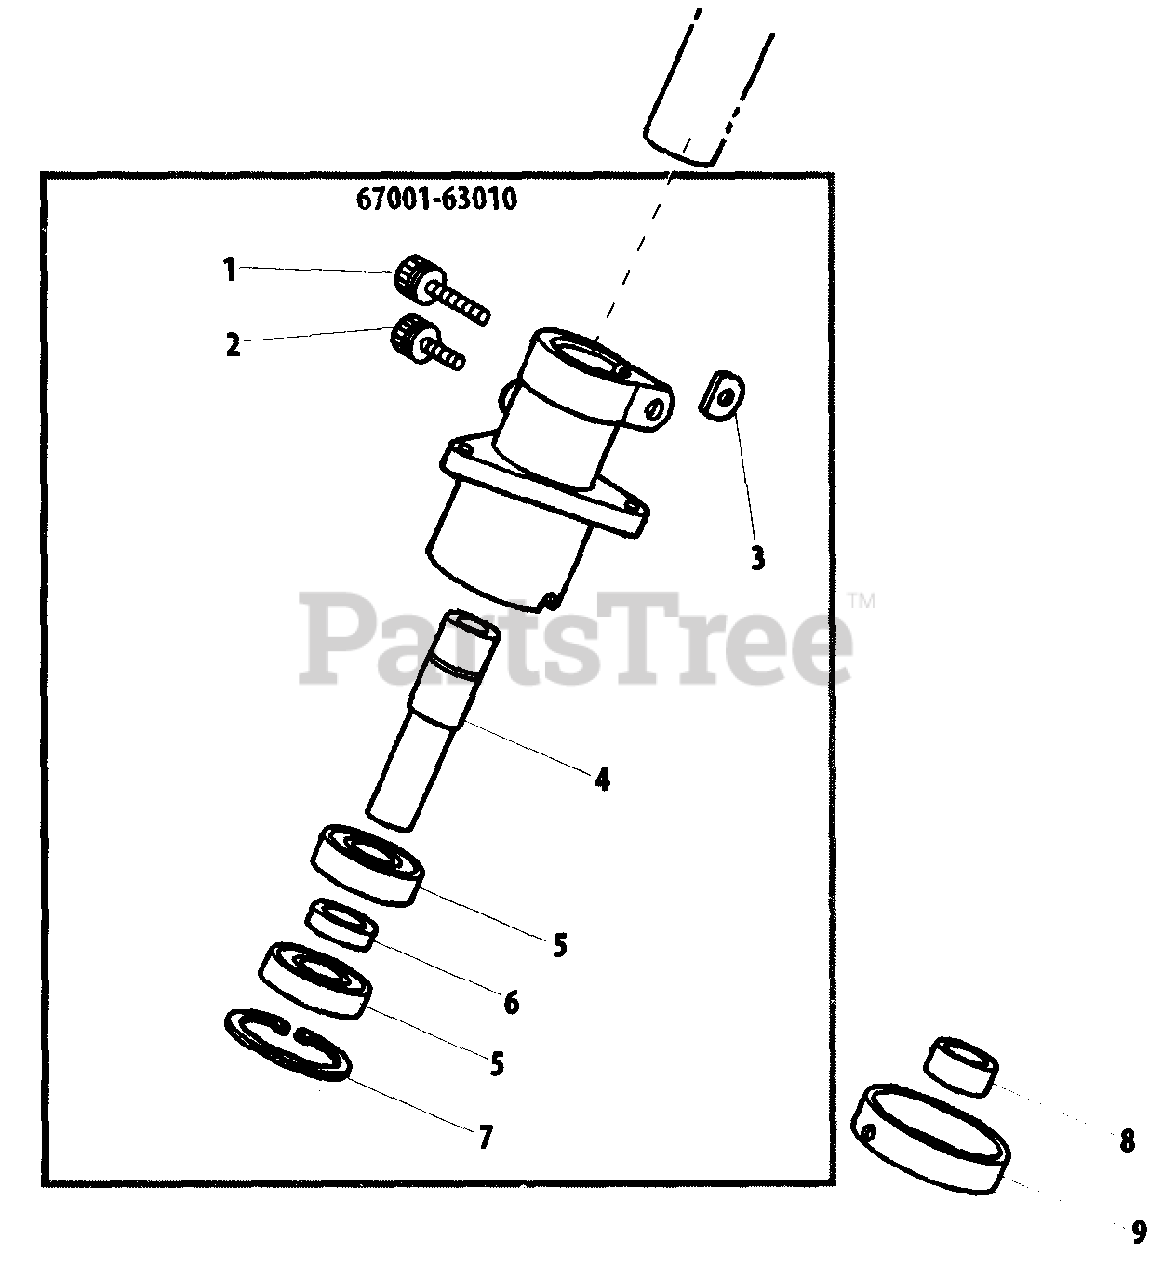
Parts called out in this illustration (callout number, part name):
1	SCREW - 5X25
2	SCREW - 5X10
3	SHIM
4	SHAFT
5	BEARING, BALL - 6001DDU
6	SPACER - UPPER
7	RING, RETAINING - 28
8	SPACER - LOWER
9	HOLDER
67001-63010	SHAFT CASE ASSY
